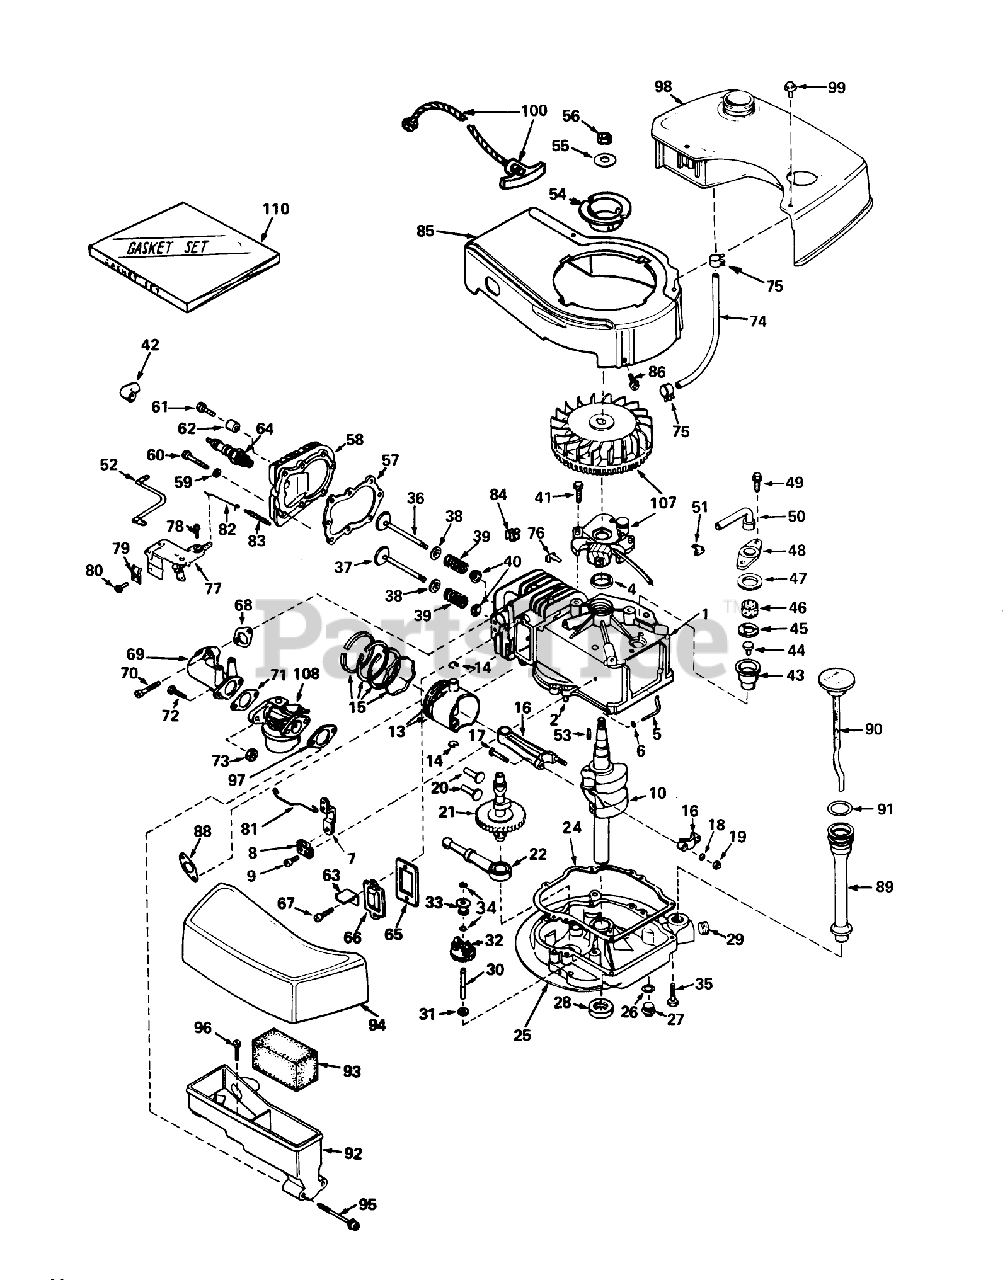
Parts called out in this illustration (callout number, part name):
1	Cylinder Assy. (Incl. Ref. #2, 4 105)
2	Pin-Dowel
4	OIL SEAL
5	Rod, Governor (Incl. No. 36)
6	Washer-Flat
7	Governor Lever
8	Clamp-Lever, Governor
9	Screw
10	Crankshaft Assembly (Incl. Nos. 12 13)
13	Piston Pin Assembly (Incl. 2 of No. 14) (.010 Oversize)
13	Piston Pin Assembly (Incl. 2 of No. 14) (.020 Oversize)
14	Ring-Retaining, Piston Pin
15	Ring Set Piston (Std.)
15	Ring Set Piston (.010 Oversize)
15	Ring Set Piston (.020 Oversize)
16	Rod Assy., Connecting (Incl. Ref. #17)
17	Bolt, Connecting
18	Washer
19	LOCKNUT
20	Lifter-Valve
21	Camshaft (Mech. Compression Release)
22	Oil Pump ASM
24	Gasket, Mounting
25	Filter, Air Cleaner
26	Gasket-Oil Drain
27	Plug Oil Drain
28	Seal Oil
29	Plug Oil Drain
30	Shaft-Governor
31	Washer-Flat
32	Governor Gear ASM
33	Spool-Governor
34	Ring-Retaining
35	Screw (1/4-20 x 1-1/4)
36	Valve, Intake (Incl. Ref. #38, 39 40) (Std.)
36	Valve, Exhaust (1/32" Oversize) (Incl. Nos. 8, 9 10)
37	Valve, Exhaust (Standard) (Incl. Nos. 8, 9 10)
37	Valve, Exhaust (1/32" Oversize) (Incl. Nos. 8, 9 10)
38	Cap-Upper Valve Spring
39	Spring-Valve
40	Cap-Valve, Spring
41	Screw
42	Cover-Spark Plug
43	Body Breather Tube
44	Valve Check
45	2000A37 WIZARD ROTA
46	Element-Breather
47	Gasket-Breather
48	Cover Breather
49	Screw, Hex Hd. w/Conical
50	Tube, Breaker
51	Clip, Breather
52	Wire, Ground
53	Key Flywheel
54	Pulley Starter
55	Washer-Spring
56	Hex Nut
57	63573 GIL 42 SNWTHW
58	Head Cylinder
59	Washer
60	Screw
61	Screw Hex Hd. Cap
62	Space
63	Retainer Clip
64	Plug, Spark (J17LM or equiv.)
65	Gasket-Breather
66	Cover-Valve
67	Screw
68	Gasket, Intake
69	Pipe, Intake
70	Screw (1/4-20 x 1)
71	Gasket-Carburetor
73	Nut and Lock Washer (1/4-28)
74	Line-Fuel
75	Clamp-Line, Fuel
76	Clip-Wire
77	Control Assy., Speed
78	Screw (10-24 x 3/4)
79	Conduit
80	Screw (10-32 x 3/8)
81	Link Governor
82	Link Governor Spring
83	Spring Governor
84	51004 GIL ROTARY TI
85	53024/VAR.GT O/P W/
86	Screw
88	Gasket Exhaust
89	Tube, Oil Filler
90	Dipstick, OiI (Incl. No. 91)
91	O-Ring
92	Body Air Cleaner
93	Filer, Air
94	Cove, Air Cleaner
95	Screw Fil Hd.
96	Screw, Hex Hd.
97	Gasket-Air Cleaner
98	Tank Fuel
99	Screw (10-32 x 35/64)
100	Rope Assy., Starter
107	Magneto
108	Carburetor (Incl. No. 71)
110	53024/VAR.16HP O/P
